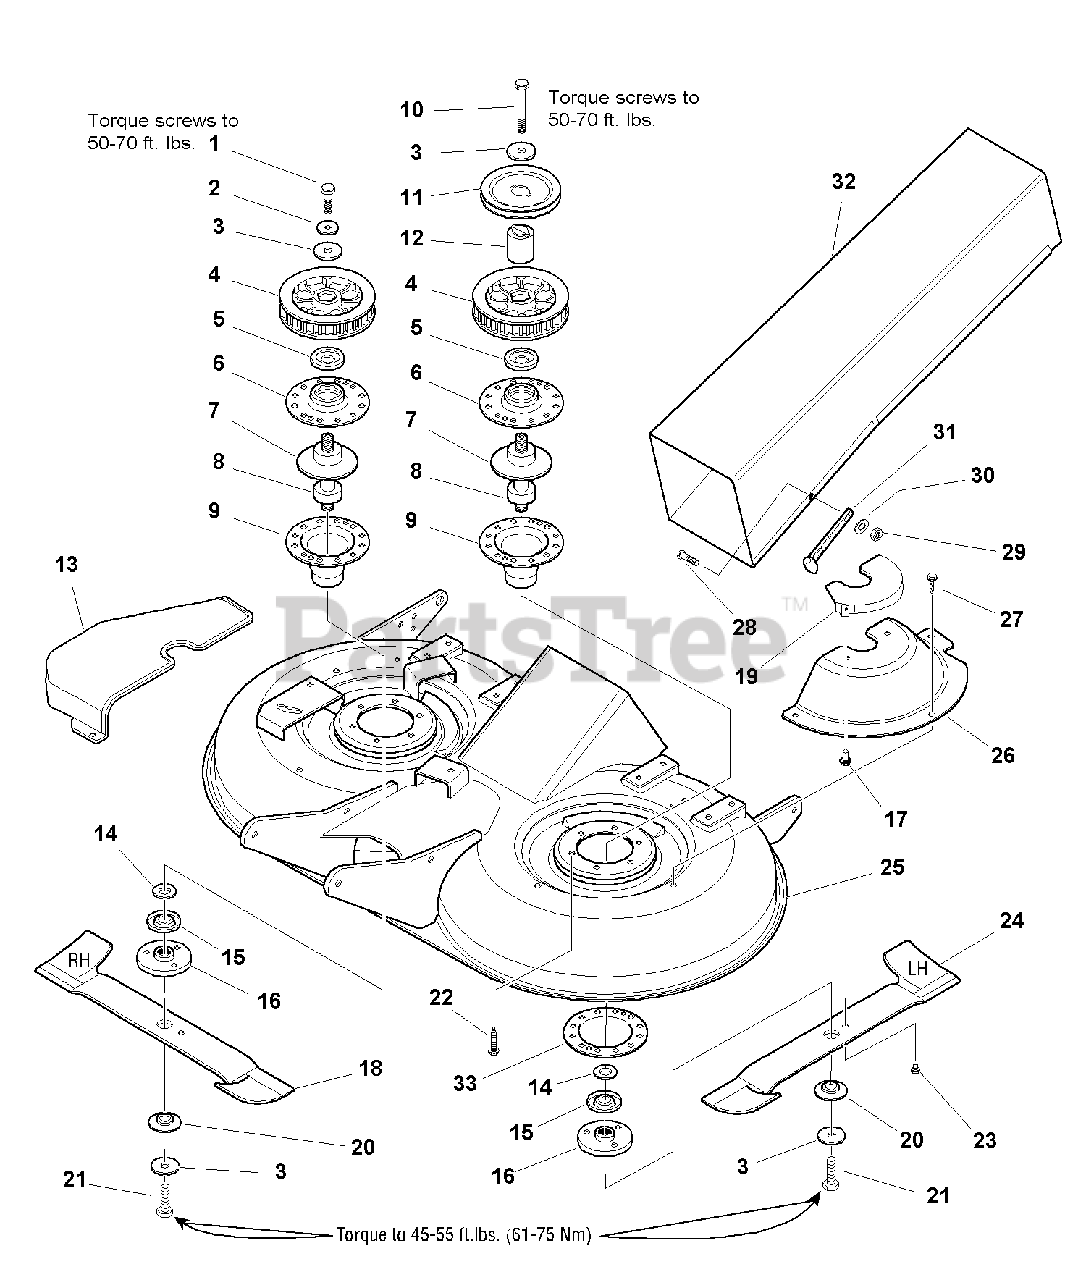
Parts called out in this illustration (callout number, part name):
1	CAPSCREW, Hex Head, 7/16-14 x 2-3/4 G8
2	WASHER, 7/16
3	WASHER, Spring, 1-3/4
4	SPROCKET & FLANGE ASSEMBLY, Rivited
5	SHIELD, Bearing Upper, Arbor
6	HOUSING, Arbor Top
7	GASKET, Foam
8	ARBOR SHAFT & BEARINGS ASSEMBLY
9	HOUSING, Arbor Bottom w/Lube Fitting
10	CAPSCREW, Hex Head, 7/16-14 x 4-1/2 G8
13	COVER, Arbor RH
14	WASHER, Shim
15	SHIELD, Bearing, Mower Arbor Lower
16	ADAPTER, Blade 26, 30, 36, 42 & 48
18	BLADE, Mower RH
19	GUARD ASSEMBLY
20	WASHER, Spline
21	CAPSCREW, Hex Head, 7/16-14 x 2-1/4 G8
22	CAPSCREW, Hex Washer Head, Taptite, 5/16-18 x 1
24	BLADE, Mower LH
25	HOUSING ASSEMBLY, 40" Mower, 2 Spindle, Orange
25	HOUSING ASSEMBLY, 40" Mower, 2 Spindle, Red
26	COVER, Arbor LH
27	CAPSCREW, Hex Washer Head, Taptite, 5/16-18 x 1/2
28	CAPSCREW, Truss Head, Phillips, #10-24 x 3/4
29	NUT, Hex Nylock, 10-24
30	WASHER, 3/16
31	STRAP, Hood, Black Rubber, 4.8" Long
32	TUBE ASSEMBLY, Top & Bottom Rear
33	ARBOR ADAPTOR
